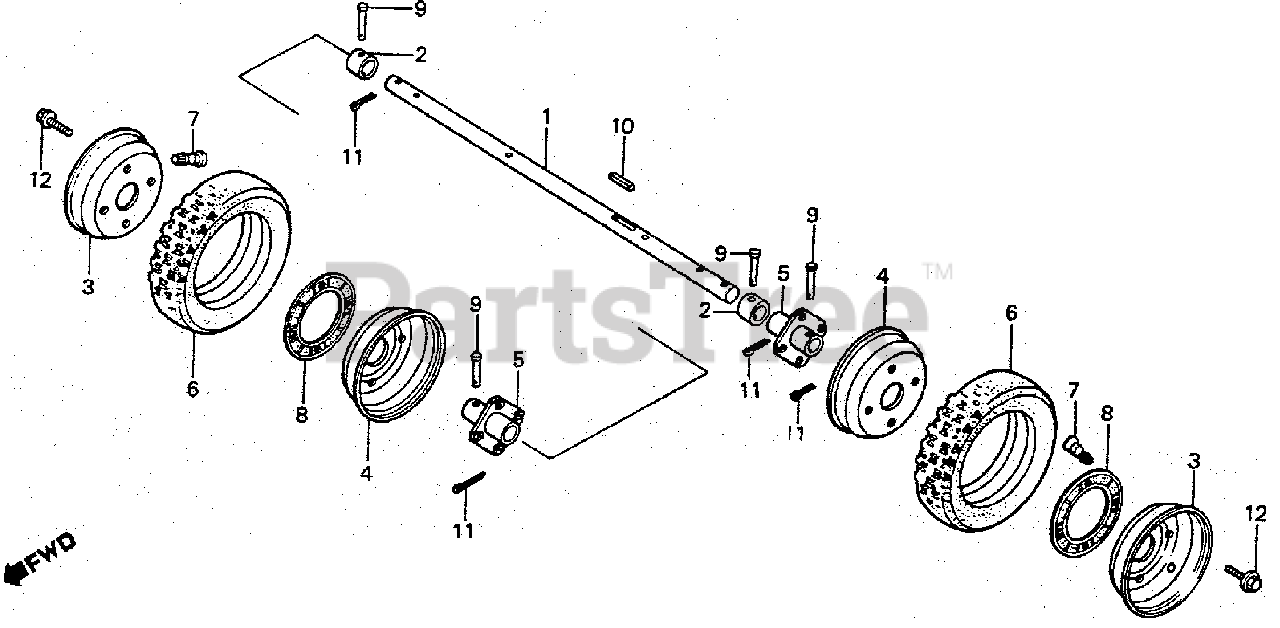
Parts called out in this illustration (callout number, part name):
1	SHAFT, WHEEL
2	COLLAR, WHEEL SHAFT
3	WHEEL A (3SPWX6DCT)
4	WHEEL B (3SPWX6DCT)
5	HUB, TIRE (HA-TYPE)
6	TIRE (14X4.0-6)
7	VALVE, RIM (SCHRADER)
7	VALVE, RIM (BS)
7	VALVE, RIM (TAIHEIYO)
8	GASKET (U-75)
9	PIN (6.2X38)
10	KEY (5X5X21)
11	PIN, COTTER (3.0X18)
12	BOLT, FLANGE (8X16)
